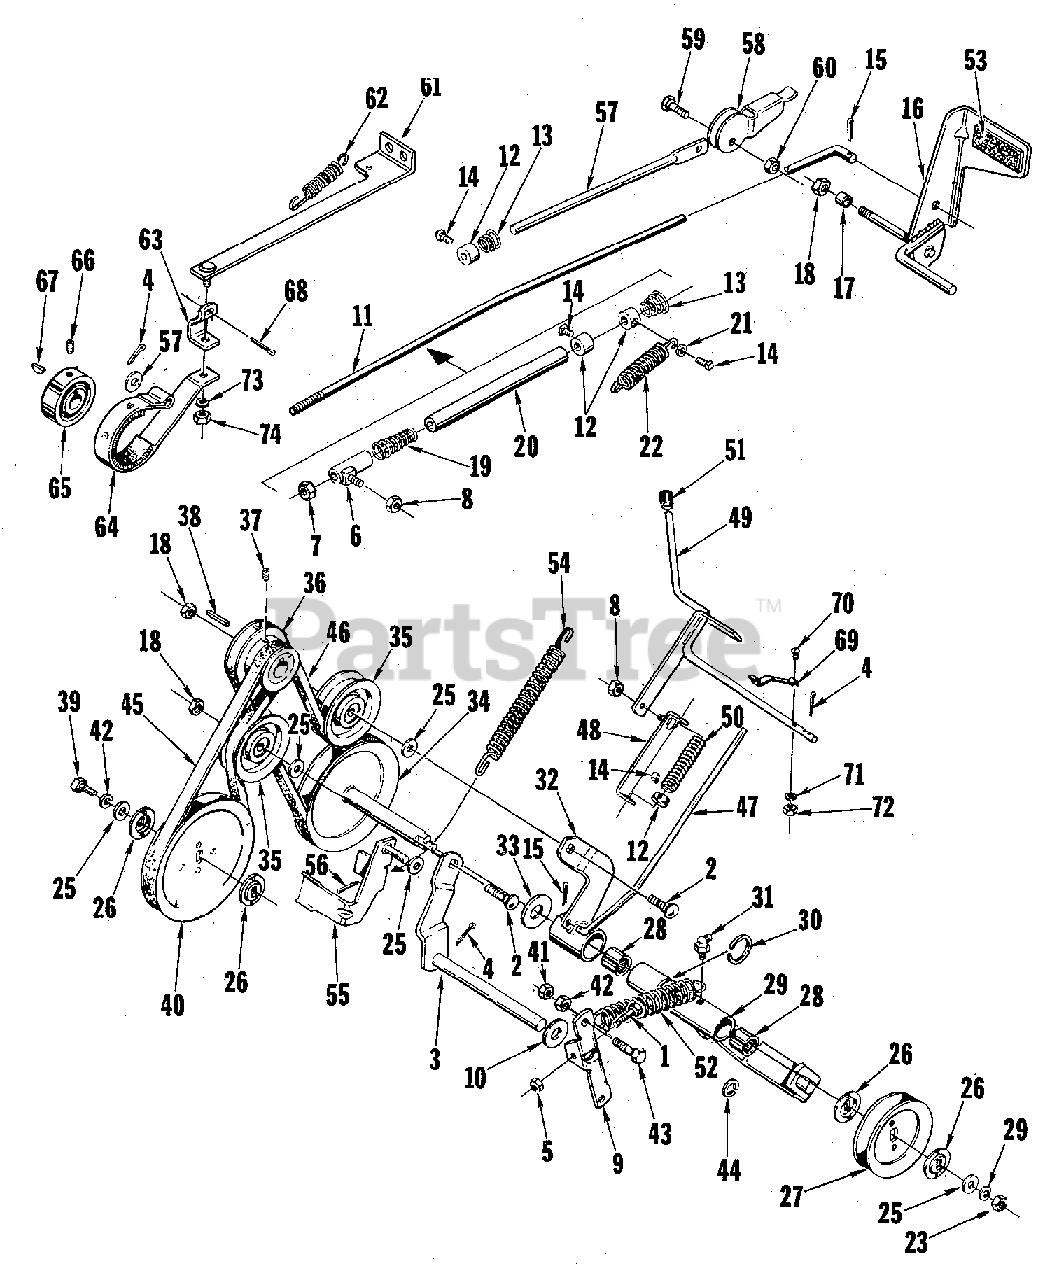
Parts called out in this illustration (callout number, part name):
1	SCREW, Hex Cap, 1/4-20 x 1
2	BOLT, Carriage, 3/8-16 x 1
3	ARM, Idler Pulley
4	PIN, Cotter, 1/8 x 1
5	NUT, Hex Lock, 1/4-20
7	NUT, Elastic Stop, 5/16-18
8	NUT, Hex Lock, 5/16-18
9	LEVER, Brake & Clutch
10	WASHER, Flat, 17/32
11	ROD, Transmission & Clutch
14	SCREW, Set, 1/4-20 x 3/8
15	PIN, Cotter, 3/32 x 3/4
18	NUT, Hex Lock, 3/8-16
19	SPRING, Compression
21	WASHER, Flat, 3/16
23	NUT, Hex, 3/8-16
24	WASHER, Lock, 3/8
25	WASHER, Flat, 5/16
26	WASHER, Special
28	BEARING, Needle
30	RING, Retaining
31	FITTING, Grease
32	LEVER, Idler
34	PULLEY & SHAFT
35	PULLEY, Idler
36	PULLEY, Engine
37	SCREW, Set, 5/16-18 x 5/16
39	SCREW, Hex Cap, 5/16-18 x 7/8
40	PULLEY, Transmission
41	NUT, Hex, 5/16-18
42	WASHER, Lock, 5/16
43	SCREW, Hex Cap, 5/16-18 x 1-1/2
44	RING, Retaining
47	ROD, Clutch, PTO
49	HANDLE, Control
52	SPRING, Idler Pulley
55	PTO BRAKE ASSEMBLY
59	SCREW, Hex Cap,, 1/4-20 x 5/8
60	NUT, Hex Lock, 1/4-20
61	GUIDE, Brake
62	SPRING, Reverse Lever
63	LEVER, Brake
66	SCREW, Set, 5/16-18 x 5/16
67	KEY, 5/32 x 5/8
68	PIN, Cotter, 3/16 x 1-1/4
69	CLIP, Spring
70	SCREW, #10-32 x 3/4
71	WASHER, Lock, #10
72	NUT, Hex, #10-32
73	WASHER, Lock, 1/4
74	NUT, Hex, 1/4-20
